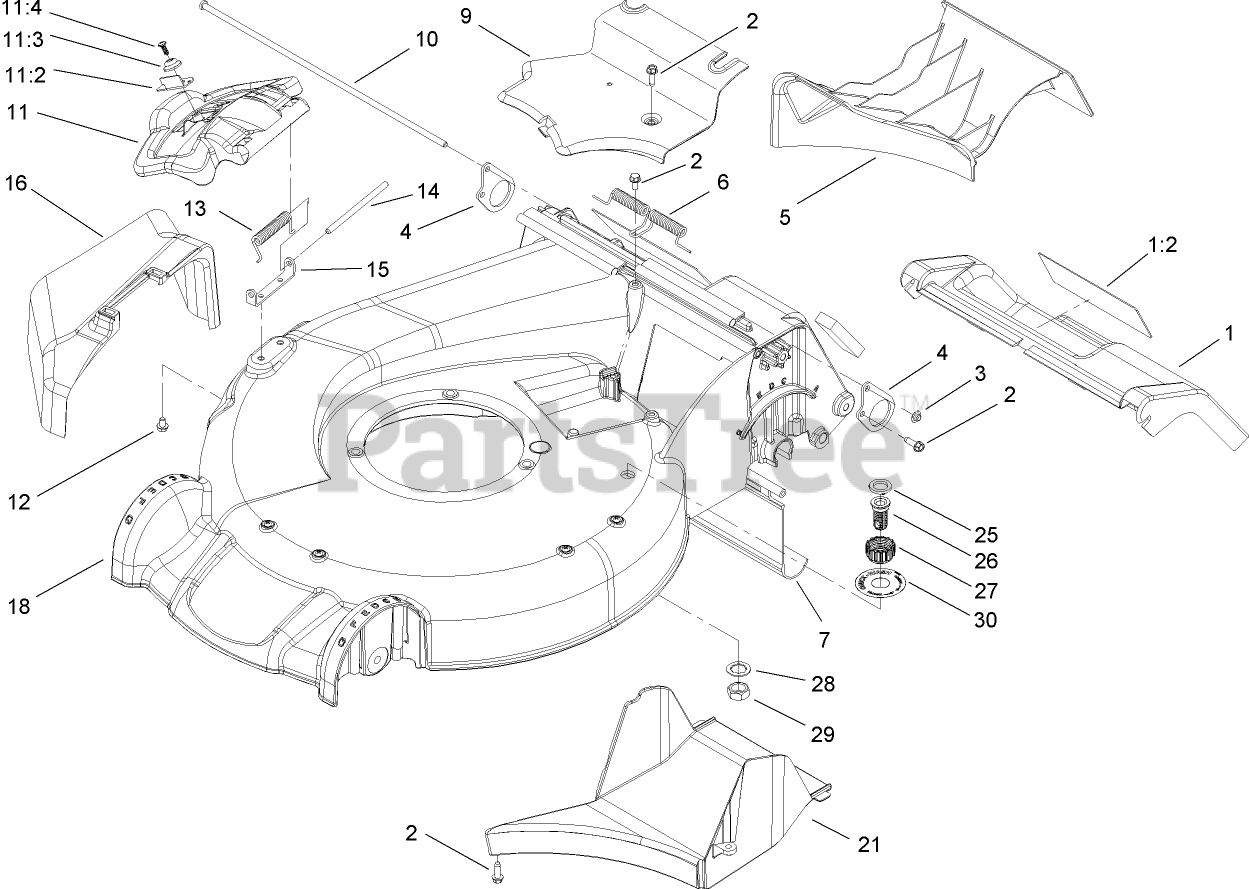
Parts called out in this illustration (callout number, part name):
1	REAR DOOR ASM
1:2	DECAL-WARNING
2	SCREW-HWHTF
3	NUT-SPEED
4	PLATE-SUPPORT, DOOR
5	MULCH PLUG ASM
6	SPRING-DOOR, REAR
9	COVER-BELT
10	ROD-SUPPORT, DOOR
11	DISCHARGE DOOR ASM
11:2	LATCH-DOOR
11:3	CAP-DOOR
11:4	SCREW-PLASTITE
12	SCREW-HWH
13	SPRING-TORSION
15	BRACKET-COVER
16	CHUTE-DISCHARGE, SIDE
21	TUNNEL-DISCHARGE
25	WASHER-SEAL, WASHOUT PORT
26	PORT-WASHOUT
27	COUPLING-HOSE, WASHOUT PORT
28	WASHER-LOCK
29	NUT-JAM
